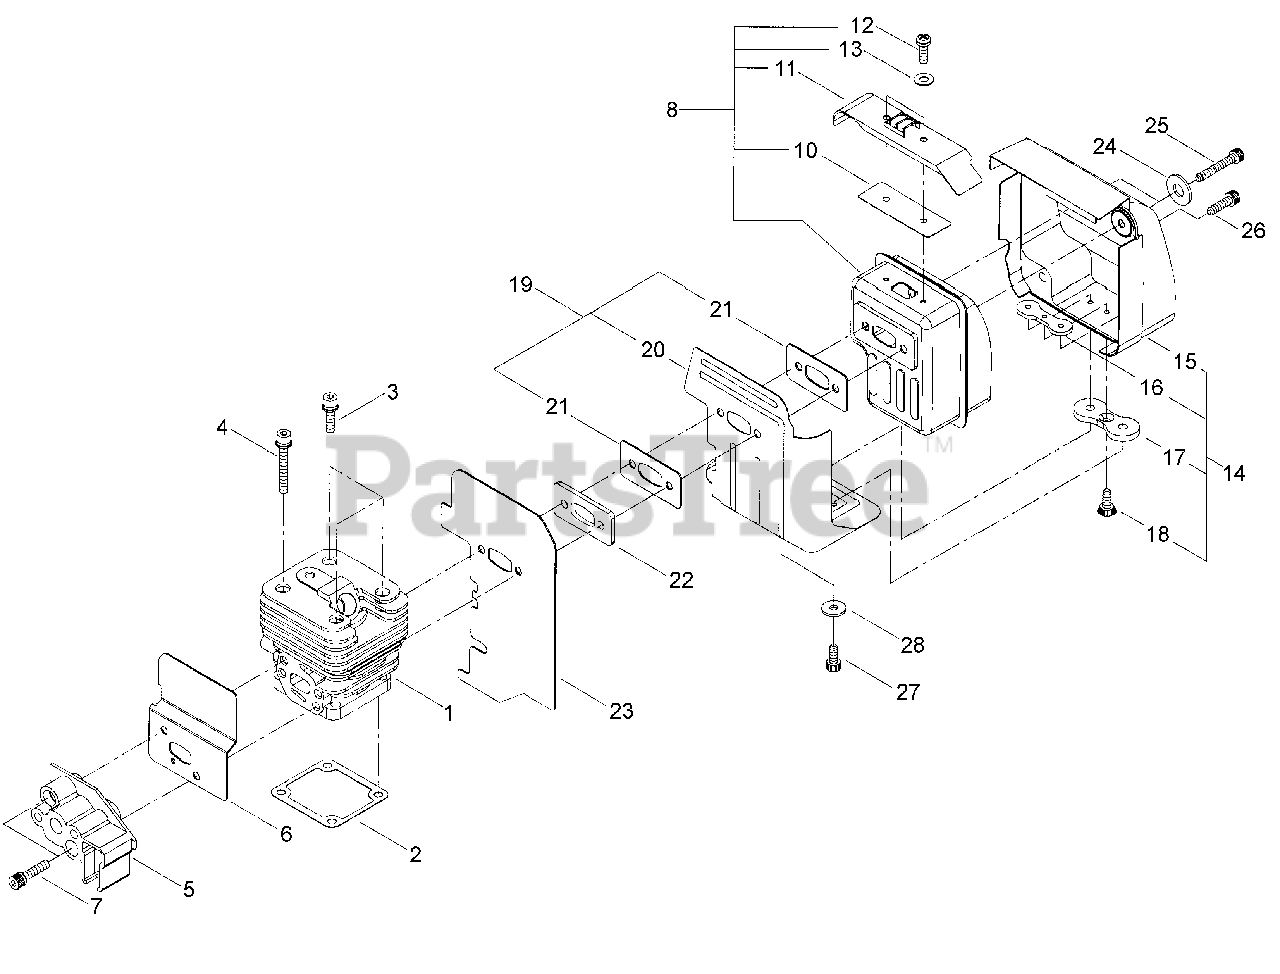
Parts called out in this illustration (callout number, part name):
1	CYLINDER
2	GASKET, CYLINDER
3	BOLT M5×16
4	BOLT M5×35
5	INSULATOR
6	HEAT SHIELD, INTAKE
7	BOLT M5×30
8	MUFFLER ASSY
10	SCREEN, SPARK ARRESTER
11	COVER, SPARK ARRESTER
12	SCREW M4×6
13	WASHER 4 MM
14	COVER ASSY, MUFFLER
15	COVER, MUFFLER
16	PLATE
18	SCREW 4×8
19	DEFLECTOR ASSY, EXHAUST HEAT
20	HEAT SHIELD, EXHAUST
21	GASKET, EXHAUST
22	SPACER
23	GASKET, MUFFLER
24	WASHER SS 5 MM
25	BOLT M5×65
26	BOLT 5×25
27	BOLT M5×10
28	WASHER Ø15ר5.2×1.6
